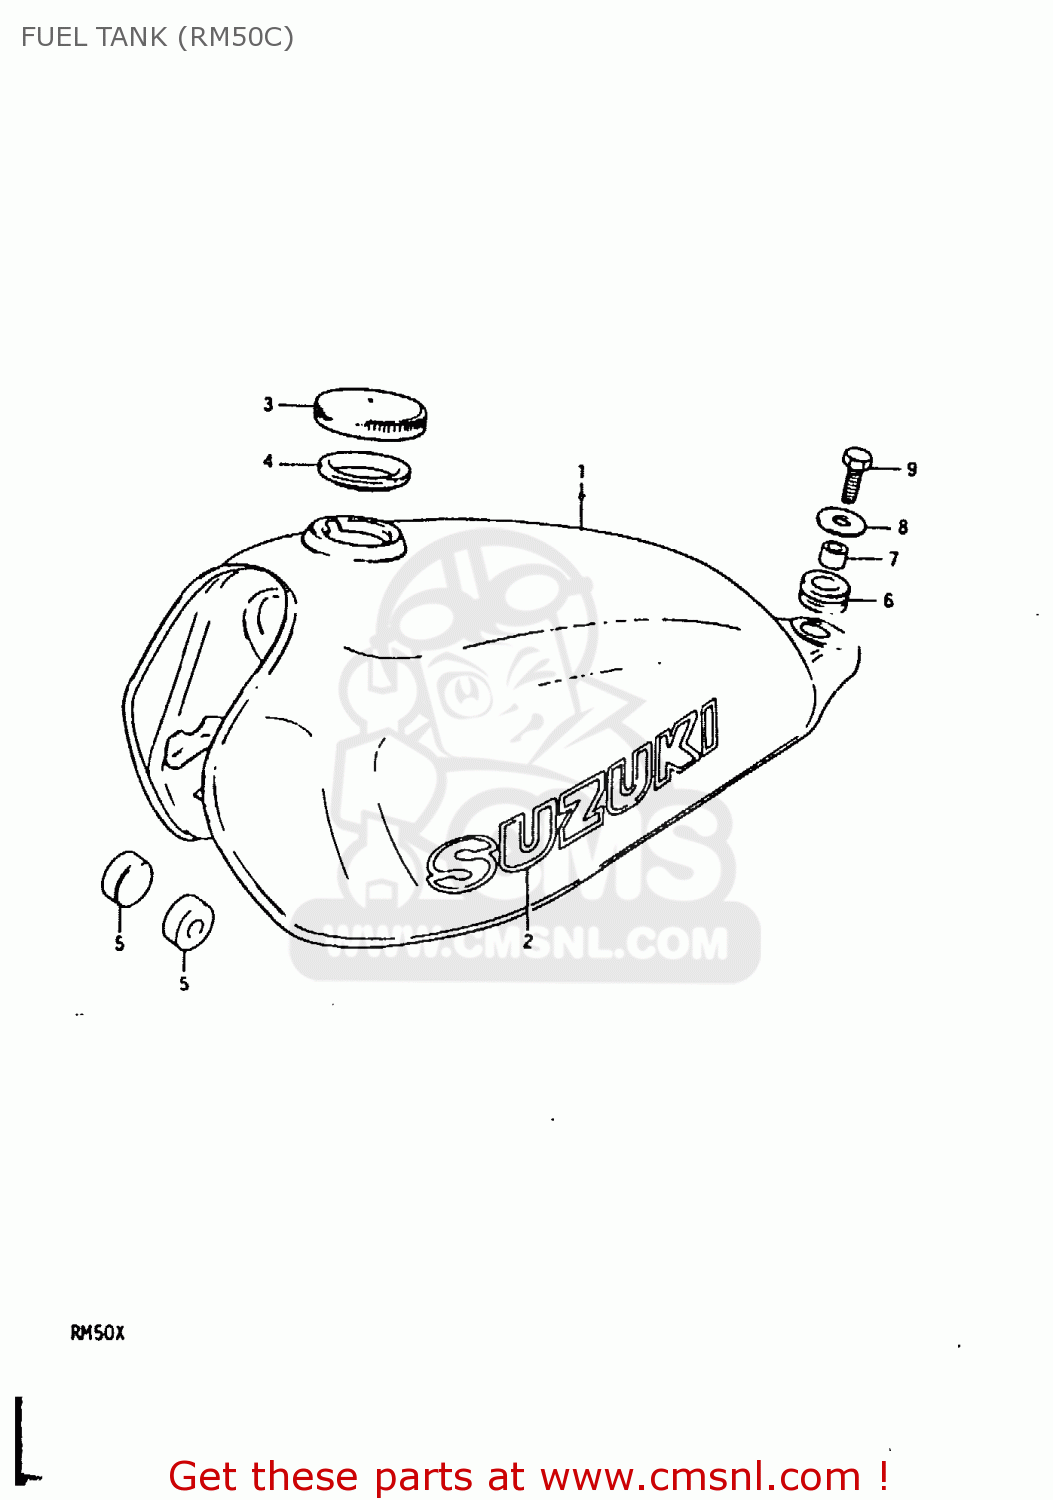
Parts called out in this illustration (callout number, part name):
1	TANK ASSEMBLY,FUEL
2	EMBLEM
3	CAP SET,FUEL TANK
4	GASKET,CAP (NAS)
5	CUSHION
6	CUSHION
7	SPACER(6.1X9X7.5)
8	WASHER (6.5X24X1.6)
9	BOLT, UPPER
